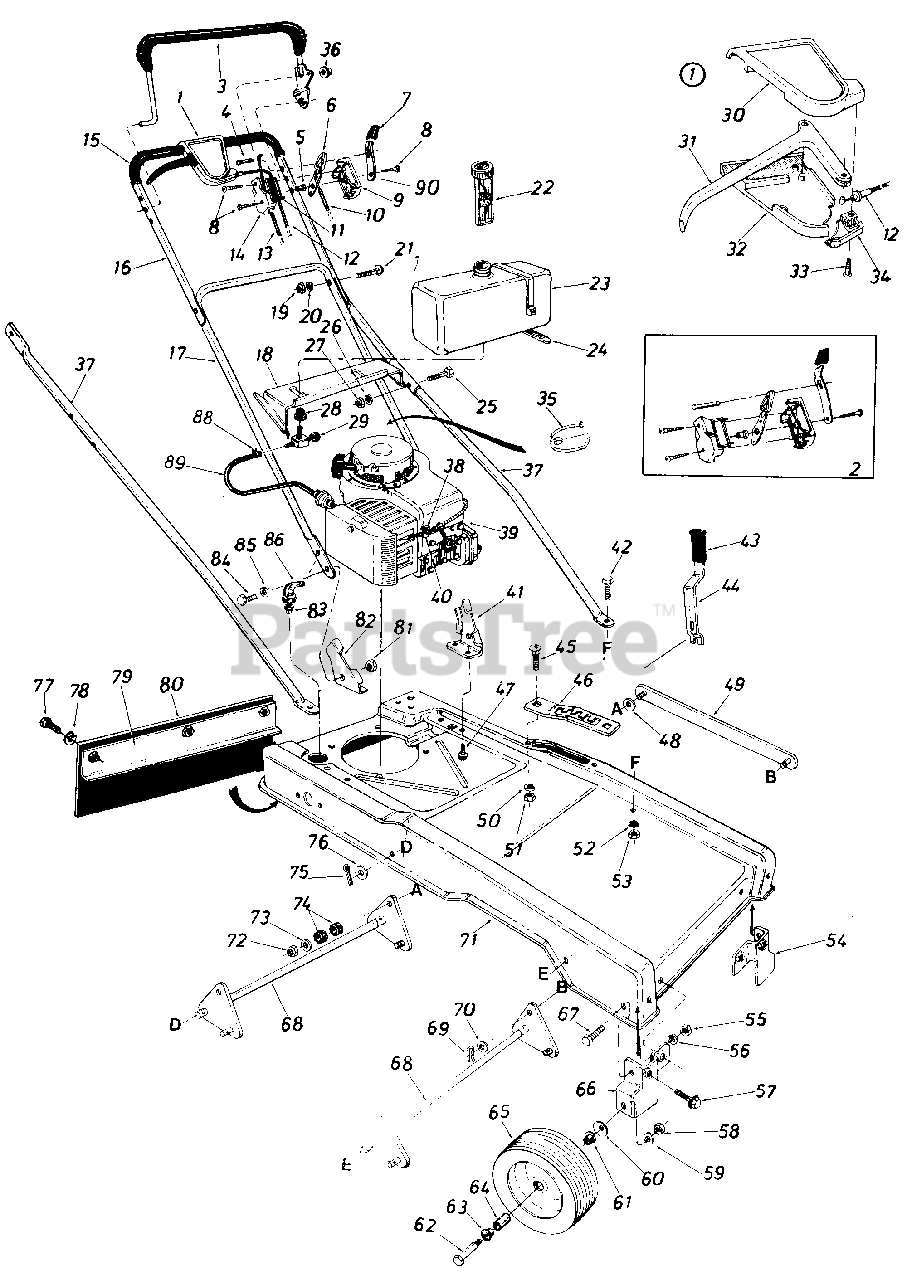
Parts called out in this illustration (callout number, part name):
1	Clutch Control Housing Comp
2	Control Housing Comp.
3	Control Handle Ass'y.
4	Lock Pin
5	Control Disc Pin
6	Throttle Control Lever
7	Spring Lever Knob
8	Truss Mach. Hi-B Tap Scr. #12 x 1.50" Lg.
9	Control Panel Half
10	Throttle Control Wire 43" Lg. -Yellow
11	Control Label-Throttle
12	Self-Propelled Cable 50" Lg.
13	Drive Clutch Cable-46" Lg.
14	Clutch Panel Half
15	Grip 22" Lg.
16	Upper Handle
17	Lower Handle
18	Gas Tank Mounting Brk't.
19	Hex Nut 5/16-18 Thd.
20	L-Wash. 5/16" I.D.
21	Carriage Bolt 5/16-18 x 1.50" Lg.*
22	Gas Gauge 1-3/4-6 x 5.50" Lg.
23	Gas Tank
24	Cable Tie 30.6" Lg.
25	Hex Bolt 5/16-24 x 1.25" Lg.*
26	L-Wash. 5/16" I.D.*
27	Hex Nut 5/16-24 Thd.
28	Bushing-Gas Tank
29	Fuel Shut-Off Valve w/Screen
30	Control Cover Half-Upper
31	Control Lever
32	Control Cover Half-Lower
33	Flat "C" Sunk Hd. Tap Scr. #10 x .75" Lg.
34	Cable Mounting Cap
35	Cable Tie
36	Push Cap
37	Strut .75" O.D. x 43.44" Lg.
38	Hex Sems Scr. #10-32 x .62" Lg.
39	Engine-5 H.P.
40	Casing Clamp
41	Handle Mount Brk't.-L.H.
42	Hex Bolt 5/16-18 x .75" Lg.
43	Grip-Black
44	Lift Handle
45	Carriage Bolt 5/16-18 x .62" Lg.*
46	Lift Handle Support Brk't.
47	Hex Wash. Hd. B-Tap Scr. 5/16-18 x .50
48	Fl-Wash. .406" I.D. x 1.25" O.D.
49	Connecting Link Ass'y.
50	L-Wash. 5/16" I.D.
51	Hex Nut 5/16-18 Thd.*
52	L-Wash. 5/16" I.D.
53	Hex Nut 5/16-18 Thd.
54	Wheel Brk't. Ass'y.-L.H.
55	Hex Nut 5/16-18 Thd.
56	L-Wash. 5/16" I.D.*
57	Hex Sems Bolt 5/16-18 x .75" Lg.
58	Hex Cent. L-Nut 3/8-16 Thd.
59	L-Wash. 3/8" I.D.
60	Bell-Wash. .400" I.D. x .88" O.D.
61	Flanged Ball Brg. 3/8" I.D.
62	Hex Bolt 3/8-16 x 2.00" Lg.
63	Flanged Ball Brg. .501" I.D.
64	Spacer .375" I.D. x .505" O.D. x 1" Lg.
65	Wheel Ass'y. Comp. 8 x 1.75
66	Wheel Brk't. Ass'y.-R.H.
67	Hex Sems Bolt 5/16-18 x .75" Lg.
68	Lift Brk't. Shaft Ass'y.
69	Intern. Cotter Pin 5/16" Dia.
70	Fl-Wash. .385" I.D. x .88" O.D.
71	Hi-Wheel Fram
72	Hex Ins. L-Nut 3/8-24 Thd.
73	Fl-Wash. .385" I.D. x .87" O.D.
74	Rubber Wash. .33" I.D. x .87" O.D.
75	Cotter Pin 1/8" Dia. x 1" Lg.*
76	Fl-Wash. .510" I.D. x 1.0" O.D.
77	Hex Bolt 1/4-20 x .62" Lg.
78	L-Wash. 1/4" I.D.
79	Retaining Strip Ass'y. 2" x 15" Lg.
80	Rear Flap 7.5 x 20" Lg.
81	Hex Nut 3/8-16 Thd.
82	Handle Mount Brk't.
83	Part of Engine
84	Hex Bolt 3/8-16 x .75" Lg.
85	L-Wash. 3/8" I.D.
86	90 Deg. Elbow Male to Female 3/8
88	Hose Clamp-.406" Dia.
89	Fuel Line 15" Lg.
90	Lockout Lever
